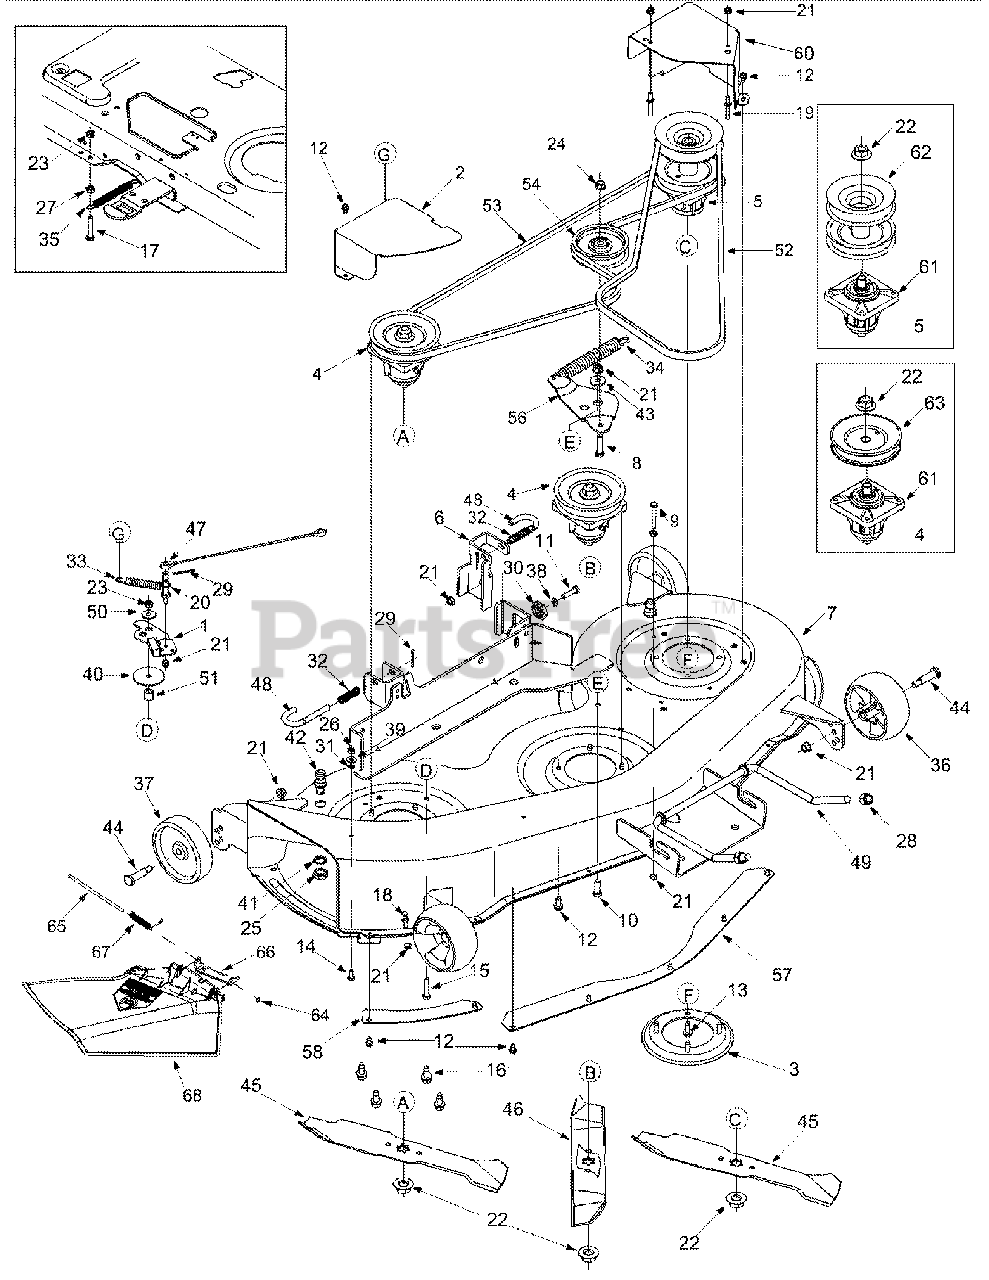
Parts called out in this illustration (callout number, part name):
1	Deck Brake Assembly
5	Spindle Assembly: Double Pulley
7	Deck 46" SD w/Nozzle Hole
8	Hex Bolt 3/8-16 x 1.5
9	Hex Bolt 1/4-20 x 2.0
10	Hex Bolt 3/8-16 x 1.0
11	Hex Bolt 5/16-18 x 1.25
12	TT Screw 1/4-20 x 0.5
13	TT Screw 5/16-18 x 0.875
14	Hex Bolt 1/4-20 x 0.620
15	Hex Bolt 5/16-18 x 1.5
16	LD Screw 5/16-18 x 0.75
17	Hex Bolt 5/16-18 x 1.75
18	Grass Catcher Pin
19	Belt Guard Pin
20	Pin 1/4-20
21	Hex Lock Nut 1/4-20
22	Flange Nut
23	Lock Nut 5/16-18
24	Flanged Lock Nut 3/8-16
25	Hex Nut M16
26	Hex Nut 1/4-20
27	Hex Nut 5/16-18
28	Lock Nut 1/2-13
29	Cotter Pin
30	Gear: Deck Adjustment
32	Compression Spring
33	Extension Spring
34	Extension Spring
35	Extension Spring
36	Deck Wheel 5.0 dia. Ball
37	Deck Wheel 5.0 x 1.38
38	Lock Washer
39	Bell Washer
40	Flat Washer
41	Lock Washer
42	Water Nozzle
43	Shoulder Spacer
44	Shoulder Screw 3/8-16
45	Blade: 16.28" Three in One
46	Blade: 14.88" Three in One
47	Cable: Bracket
48	Rod: Deck Release Handle
49	Rod: Front Adjustment
50	Shoulder Spacer
51	Spacer
52	Belt: V Type
53	Belt: V Type
54	Idler Pulley
61	Spindle Housing
62	Deck Pulley: Double
63	Deck Pulley
64	Speed Nut
65	Hinge Pin
66	Mounting Bracket
67	Torsion Spring
68	Chute Deflector: Side Discharge
